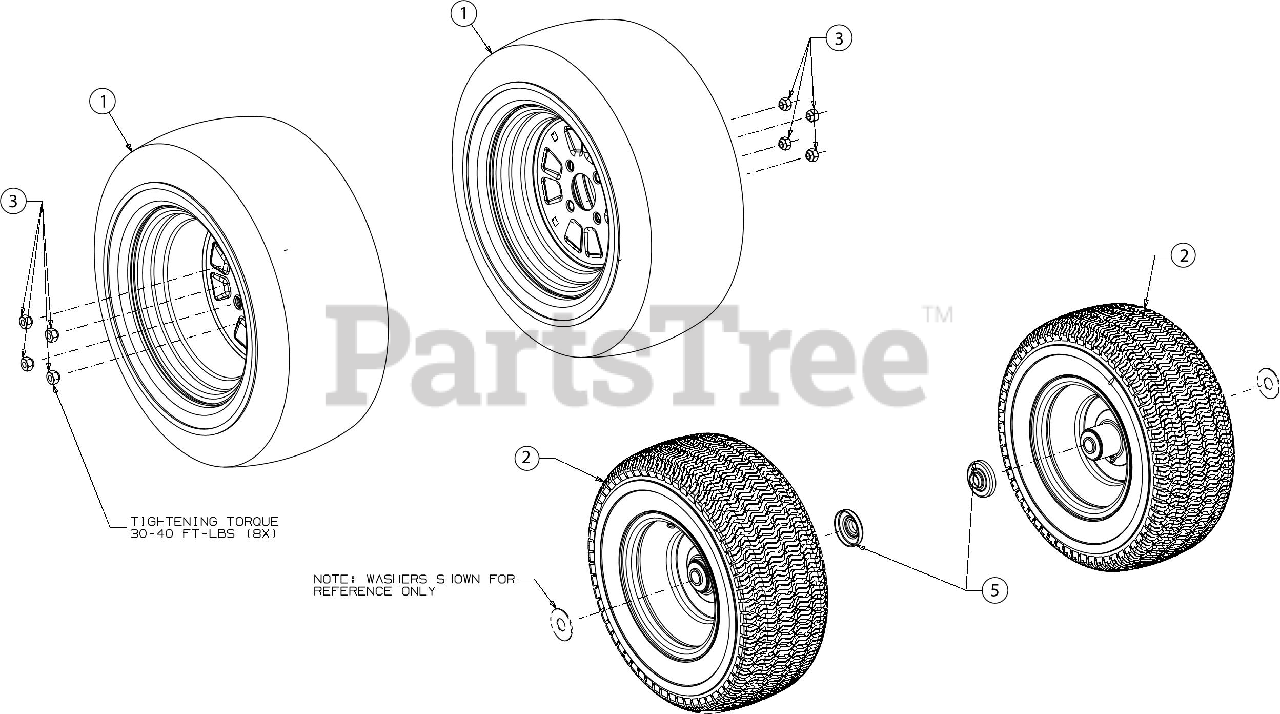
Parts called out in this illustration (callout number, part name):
1	WHEEL ASSEMBLY (22 x 9.5 x 12)
1	TUBELESS VALVE
1	RIM ASSEMBLY (12 x 7)
2	WHEEL ASSEMBLY (16X6.5X8)
2	RIM ASSEMBLY (8 x 5.38)
2	TUBELESS VALVE
2	BRG-BALL .754 ID x 1.750 OD
2	TIRE 16X6.5X8 TURF MSTR
2	LUBE FITTING
3	LUG NUT 7/16-14
5	WHEEL BEARING COVER
